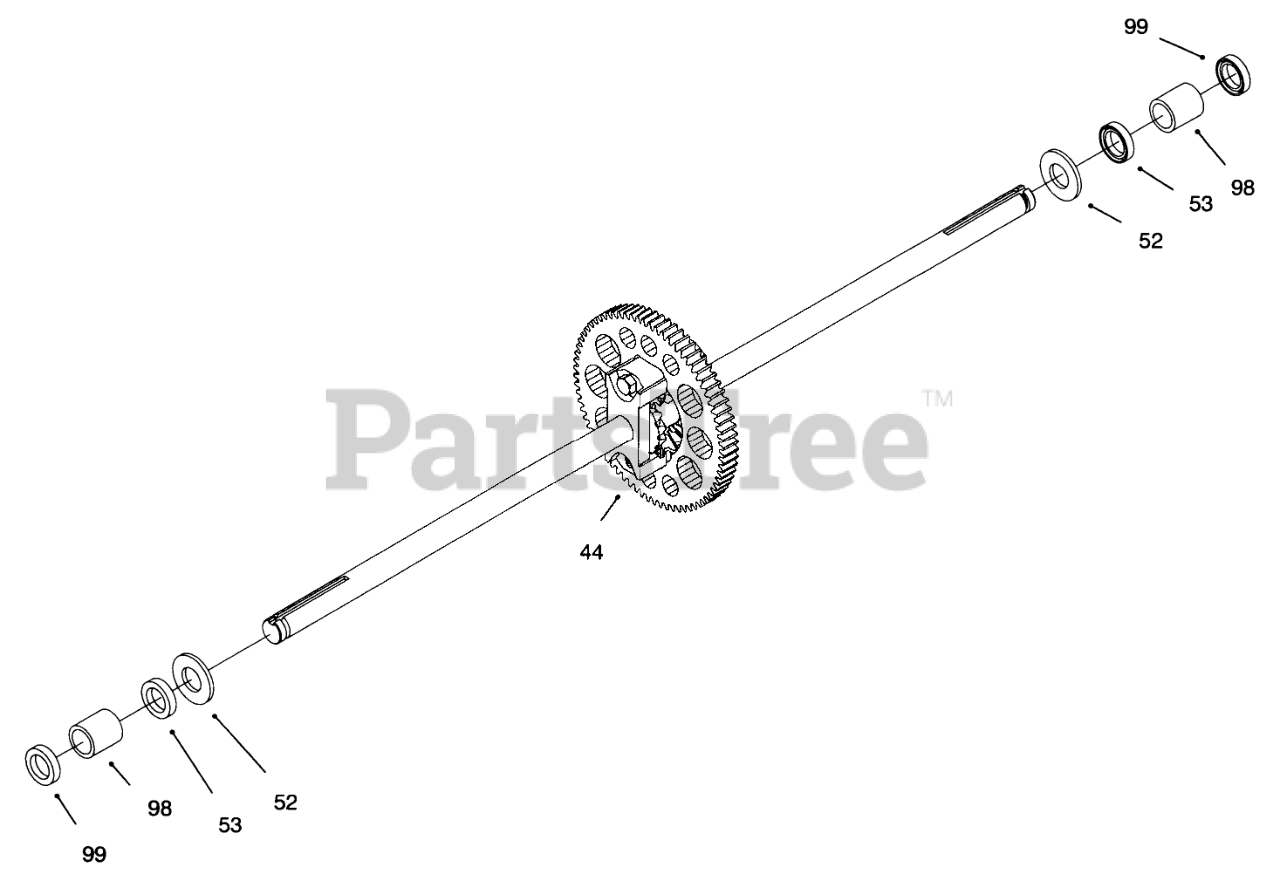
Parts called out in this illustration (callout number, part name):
44	ASM - DIFFERENTIAL
52	WASHER
53	SEAL
98	SLEEVE - BEARING
99	SEAL - WIPER
